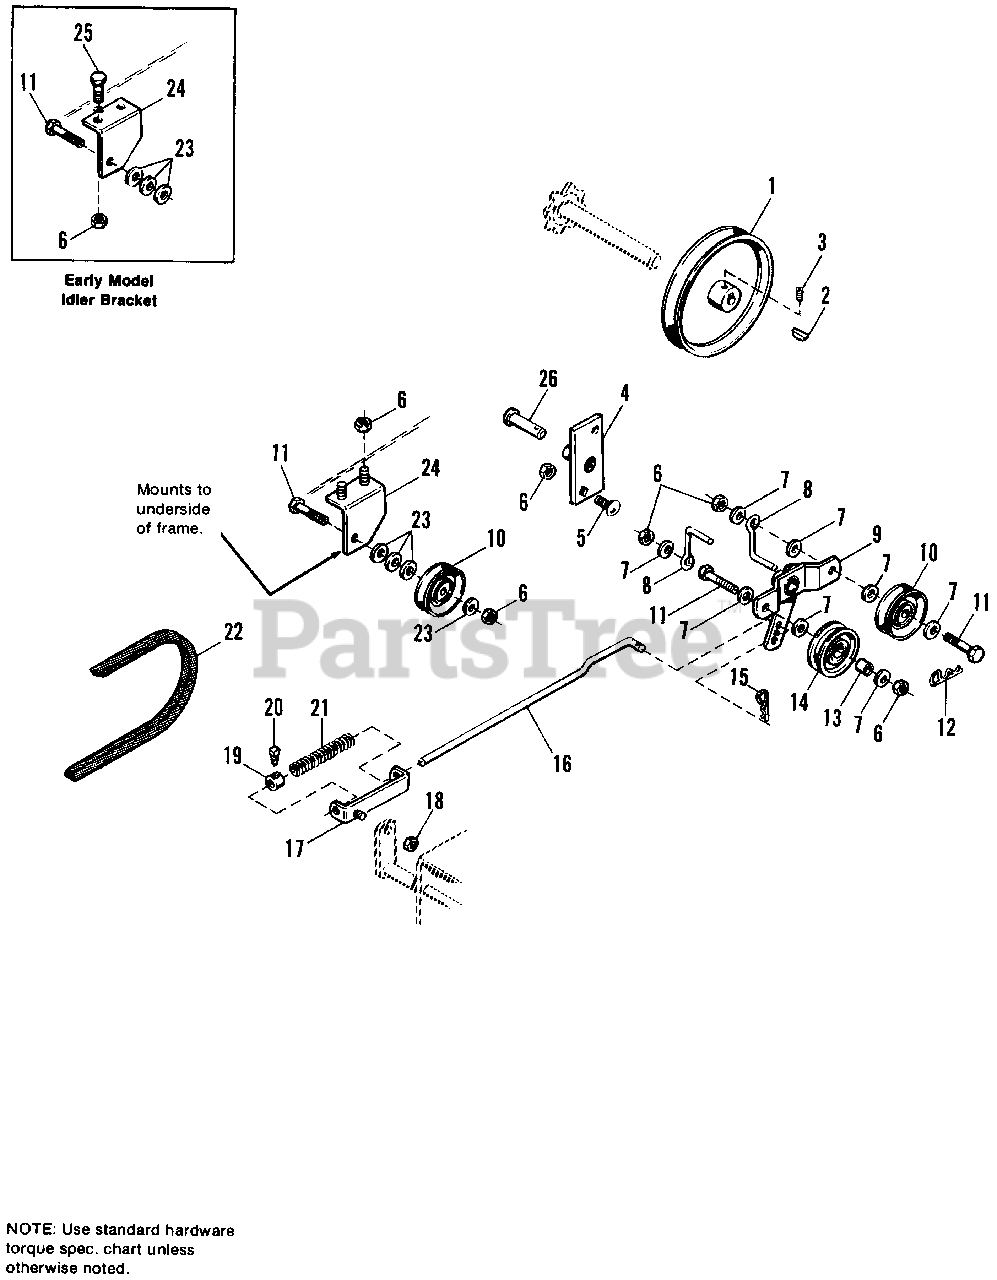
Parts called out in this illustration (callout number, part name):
1	PULLEY, Driven
2	KEY, #9, 3/16 x 3/4
3	SETSCREW, 5/16-18 x 1/2
4	BRACKET & HUB ASSY.
5	CARRIAGE BOLT, 3/8 x 3/4
6	NUT, 3/8-16
7	WASHER, 3/8 x 1 x 1/8
8	GUIDE, Belt
9	BRACKET ASSY., Idler
10	PULLEY, Idler
11	CAPSCREW, 3/8-16 x 1-3/4
12	PIN, Quick, Hairpin
14	PULLEY (Flat-side)
15	PIN
16	ROD, Clutch
18	NUT, 5/16-18
20	SETSCREW, 1/4-20 x 3/8
22	BELT, "V" Rear
23	WASHER, 5/16
24	BRACKET, Idler (Early Models)
24	BRACKET, Idler (Later Models)
25	CAPSCREW, Hex, 3/8-16 x 3/4 (Later Models only)
26	PIN, Clevis
